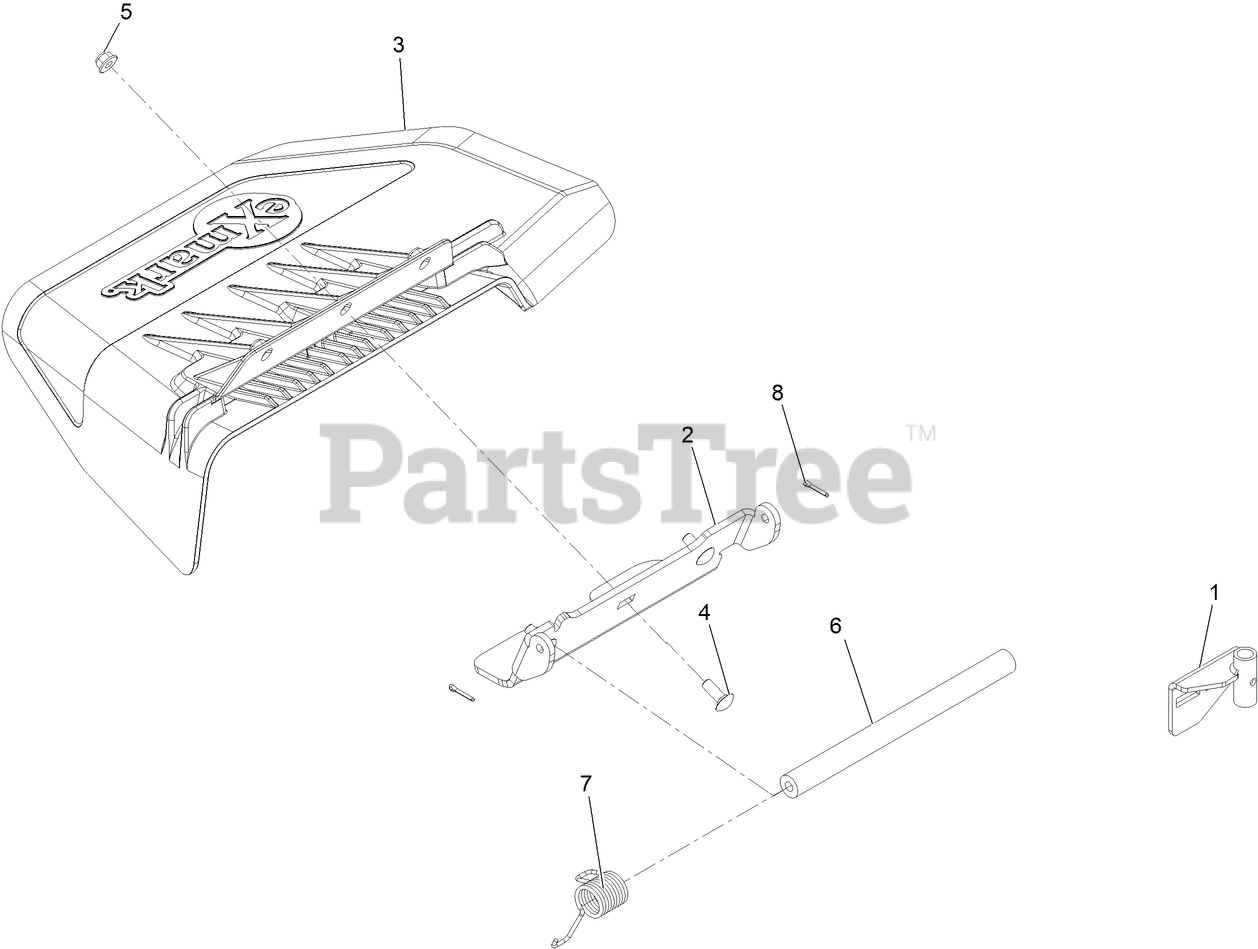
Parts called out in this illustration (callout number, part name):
1	Mount-Pin, Ocd [red]
2	Mount-Chute, Ocd
3	CHUTE- DISCHARGE
4	SCREW-CARR
5	NUT-HF, NI
6	Spacer-Deflector, Mounting
7	SPRING-TORSION
8	PIN-COTTER
